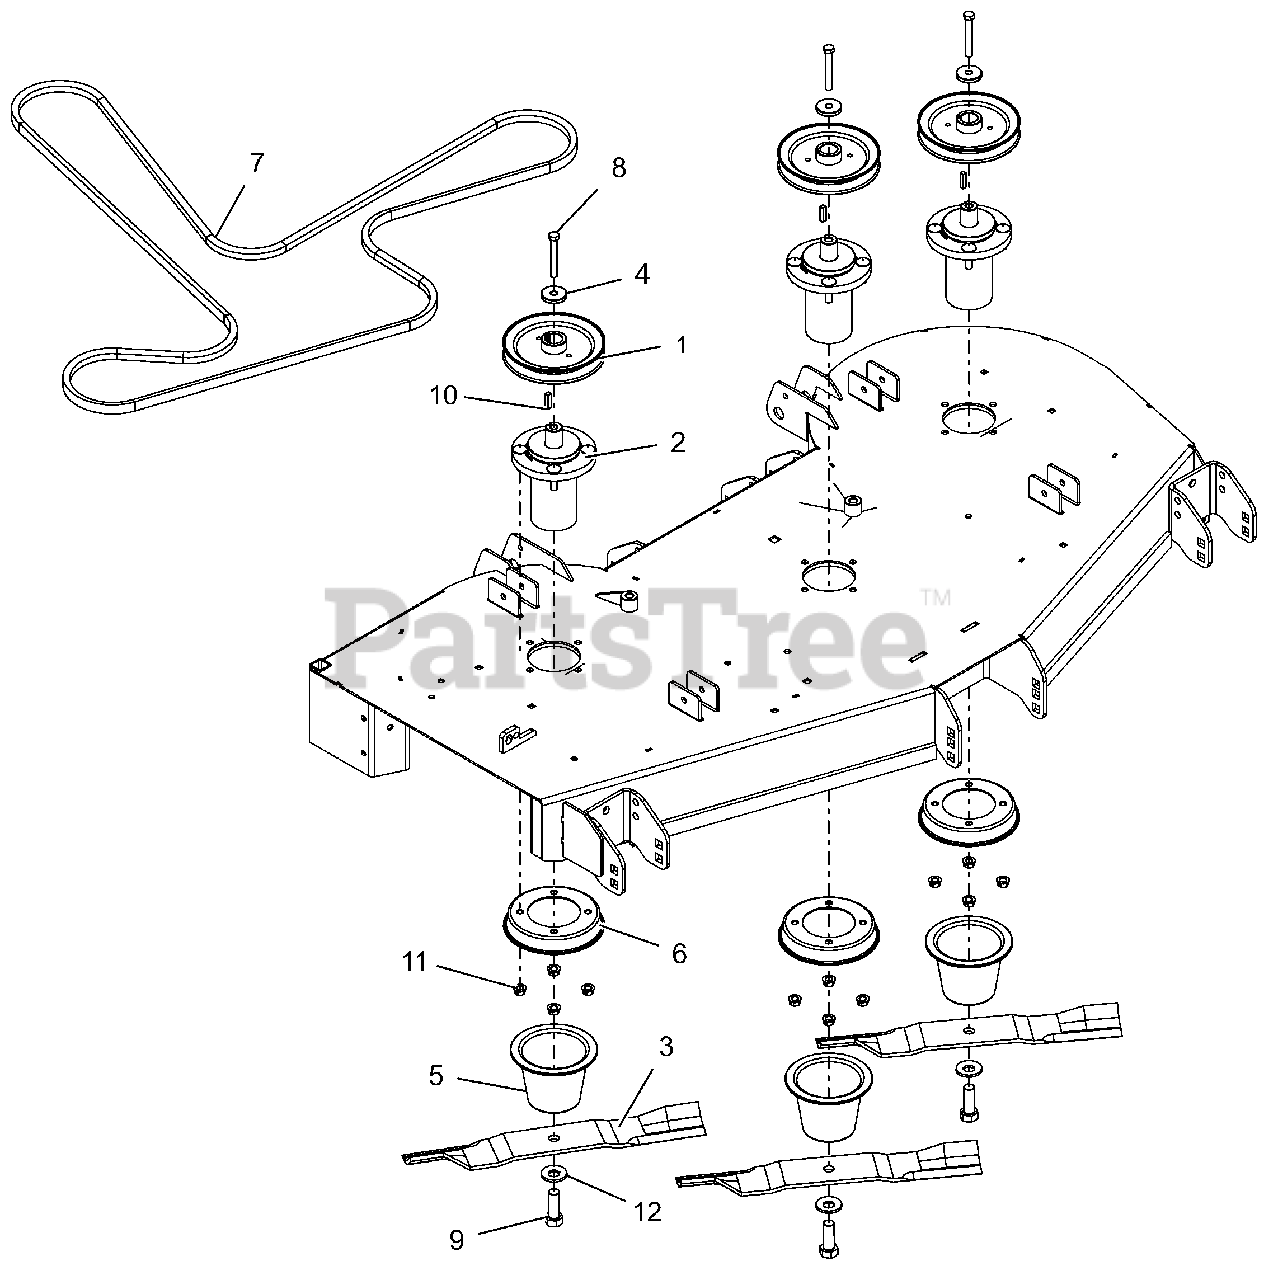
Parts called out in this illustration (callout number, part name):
1	PULLEY, V-1" ID X 6.00 OD
2	ASM, MAINT FREE ALUM SPINDLE
3	BLADE, 18.00" MOWER (HI-LIFT)
4	RETAINER, SHEAVE
5	GUARD, SPINDLE LOWER
6	GUARD, SPINDLE TOP
7	V-BELT, B RAW EDGE EPDM
8	BLT-HEX .38-16X2.75 GR8 YWZC
9	BLT-HEX .62-18X1.75 GR8 YWZC
10	KEY, SQ .25X.25X1.00 RC 40-50
11	NUT-LK-CTR-FLG .38-16 YWZC
12	WSHR-BLVL .669X1.535X.138
